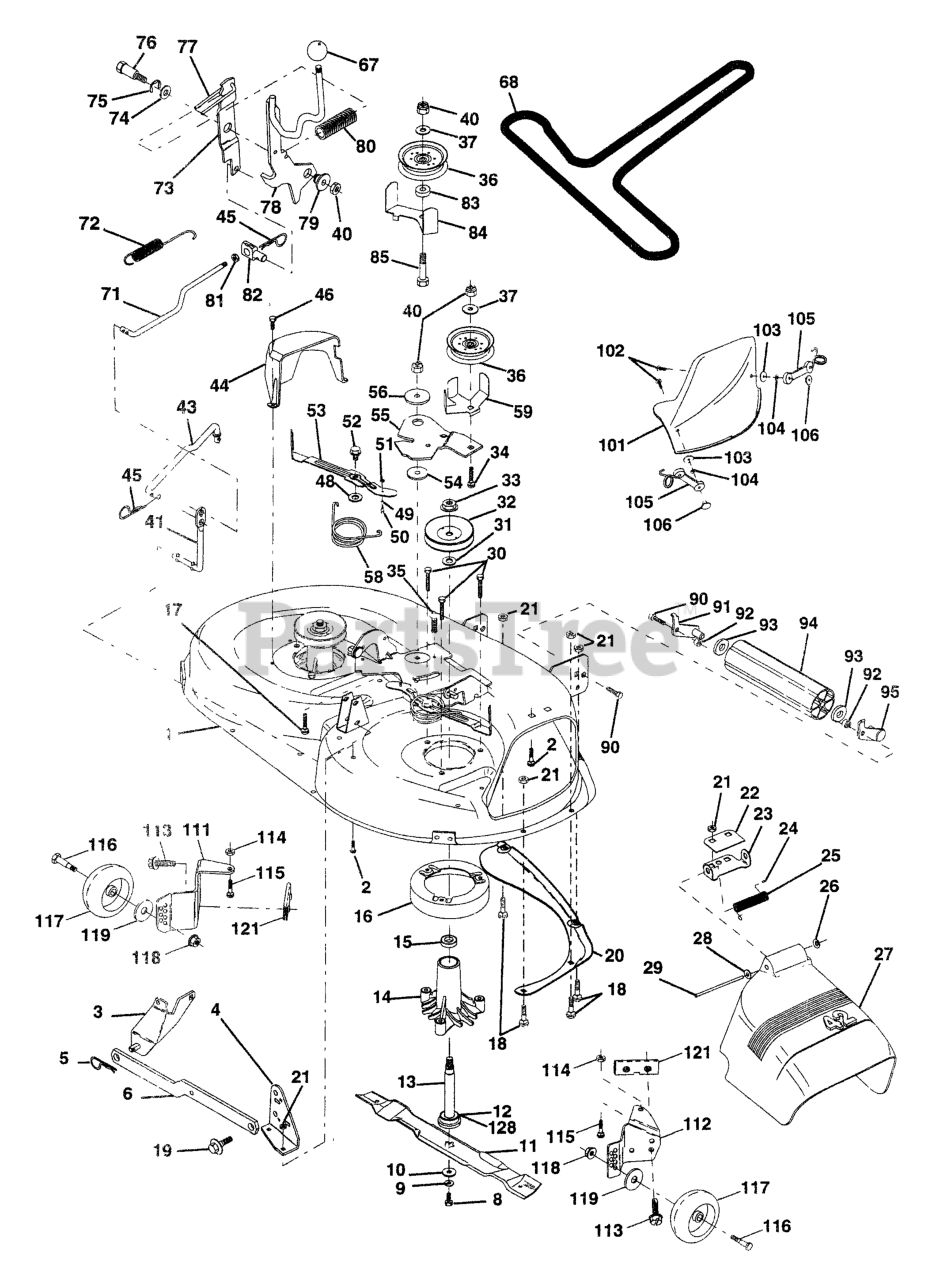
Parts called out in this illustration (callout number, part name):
1	DECK 42"
2	RP BOLT 5/16-18 X3/4 ZN/YEL GR
3	BRKT ASM SWAY BAR
4	BRKT DECK SW BAR
5	RETAINER-SPRNG RB
6	REAR SUSP ARM
8	BLADE BOLT
9	LOCKWASHER
10	WASHER.BLADE
11	BLADE.42".MULCH
12	BEARING.BALL.#6204.(MANDREL)
13	SHAFT ASM VENT
14	HOUSING.MANDREL.VENTED (MACHD)
16	STRIPPER
17	BOLT
18	BOLT
19	BOLT SHD 5/16-18
20	BAFFLE
21	LOCKNUT
22	STIFFENER BRACKET
23	DEFLECTOR BRACKET
24	CAP-SLEEVE LT
25	SPRING TORSION
26	NUT PUSH M
27	SHIELD.DEFLECTOR.MOWER.42".BLK
28	Washer 11/32 X 5/8 X 16 Ga
29	ROD.HINGE
30	SCREW
31	WASHER
32	PULLEY/MANDREL
33	NUT
35	FASTENER.XMAS.TREE
36	FLAT IDLER PULLEY
37	WASHER
43	CLUTCH ROD
44	GUARD MANDREL LH BLACK
45	RETAINER M
46	SCREW.1/4-20X5/8
49	CAM FOLLOWER
52	BOLT.SHOULDER.5/16-18
53	ARM
54	HARDENED WASHER
55	IDLER ARM
56	SPACER RETAINER
59	GUARD, BELT
67	KNOB T (1/2-HOLE)
68	V-BELT TRIPATH
71	CLUTCH ROD
72	RETURN SPRING
73	ARM CLUTCH SECONDARY
77	KEEPER SPRING
78	CLUTCH ARM
79	BUSHING.FLANGE.E-RING.GROOVE
80	SPRING-CLUTCH (2 2 PW01)
81	NUT
82	TRUNNION.ADJUSTABLE.3/8-16
84	KEEPER BELT
85	BOLT
90	BOLT
91	BRACKET LH (A)
92	NUT
93	Washer 17/32 x 7/8 x 16 Ga.
94	NOSE ROLLER
95	BRACKET RH (B)
101	COVER MULCH 42"
102	SCREW
104	LOCKWASHER #10
105	LATCH ASSEMBLY
106	WELDNUT
111	BRACKET
112	BRACKET
113	SCREW.THDROL.5/16-18X3/4.TTY
114	NUT
115	BOLT.CARR.5/16-18X1/2
116	BOLT, SHOULDER
117	WHEEL GAGE DONUT
118	LOCKNUT
119	WASHER.5/16.FLAT.STE.STD.
121	BRACKET.EXTRUDED.GAGE.WHEEL
128	WASHER FELT
